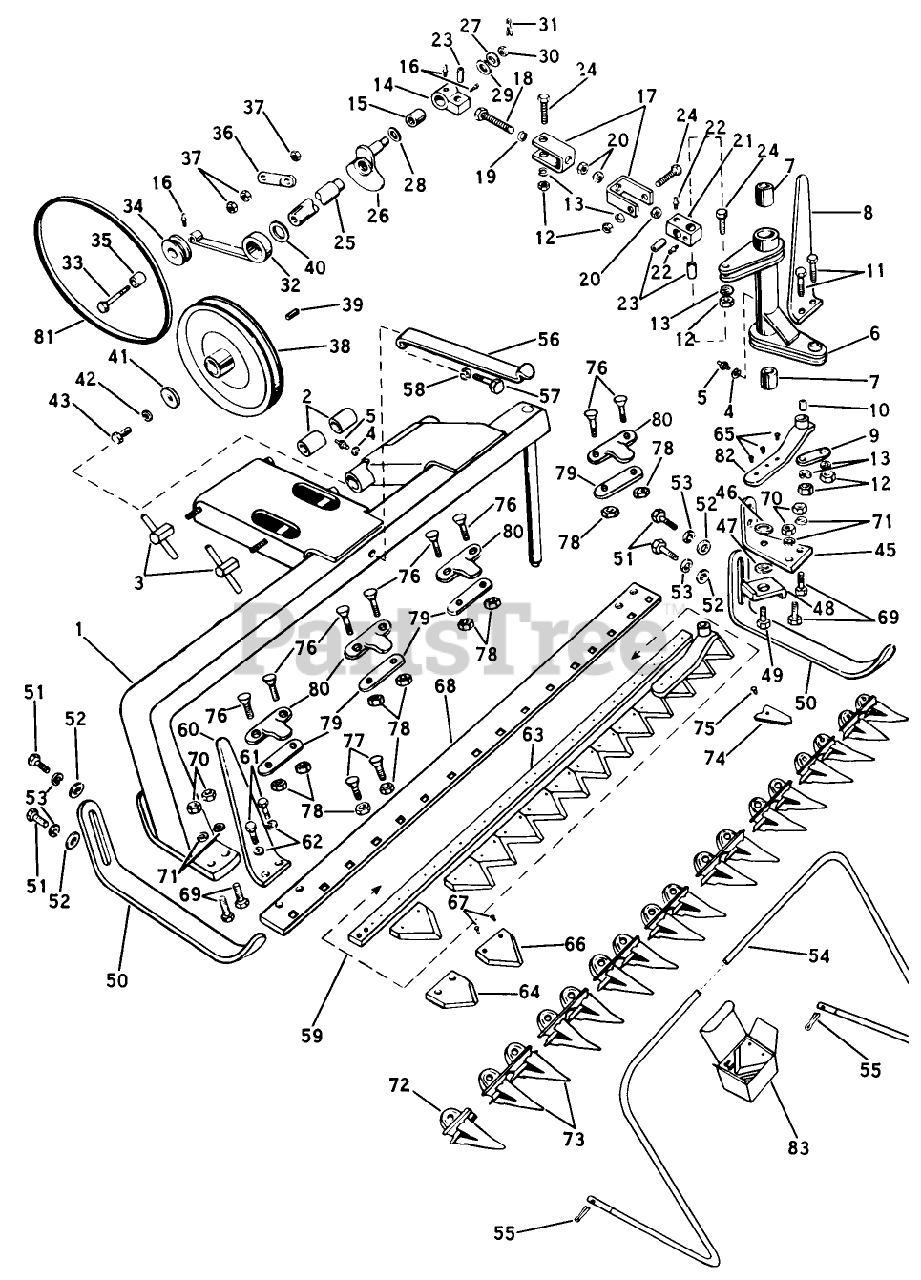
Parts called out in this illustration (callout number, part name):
1	Frame Assembly
4	Lift Bar
5	Grease Fitting
6	Oscillator Drive Assembly
8	Left Hand Grass Deflector
9	Collecting Rod Link
12	Hex Nut
13	Lockwasher
14	Connecting Rod Assembly
20	Hex Nut
21	Connecting Rod Swivel
24	Hex Head Bolt
25	Assy.-Frame
30	Slotted Nut
31	Cotter Pin
32	Idler Lever Assembly
34	Idler Pulley Assembly
36	HOSE HYDRAULIC 19"
37	Hex Jam Nut
38	Drive Pulley
43	Hex Head Bolt
51	Hex Head Bolt
54	Grass Guard
55	Cotter Pin
56	Grass Guard Brace
58	Lift Bar
59	Cutter Bar Assembly
60	Right Hand Grass Deflector
61	Capscrew
62	Lift Bar
68	Main Bar
70	Hex Nut
72	Single Guard
73	Twill Guard
74	Ledger Plate
80	Hold Down Clip
81	Lockwasher
82	Blade Bracket Assembly
83	Repair Kit
